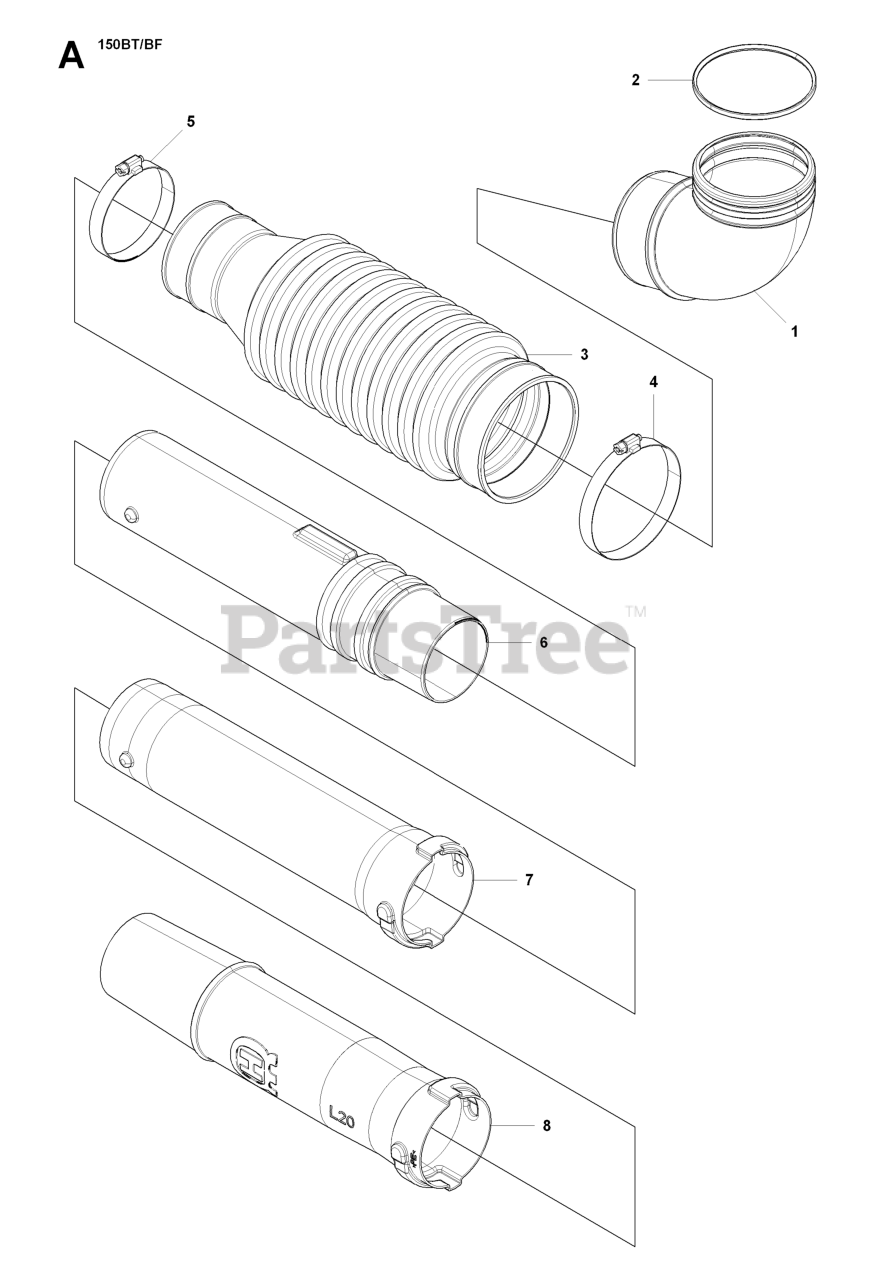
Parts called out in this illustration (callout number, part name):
1	PIPE BEND
2	O-RING
3	BELLOWS
4	CLAMP(F115)
6	SWIVEL JOINT
7	PIPE STRAIGHT
